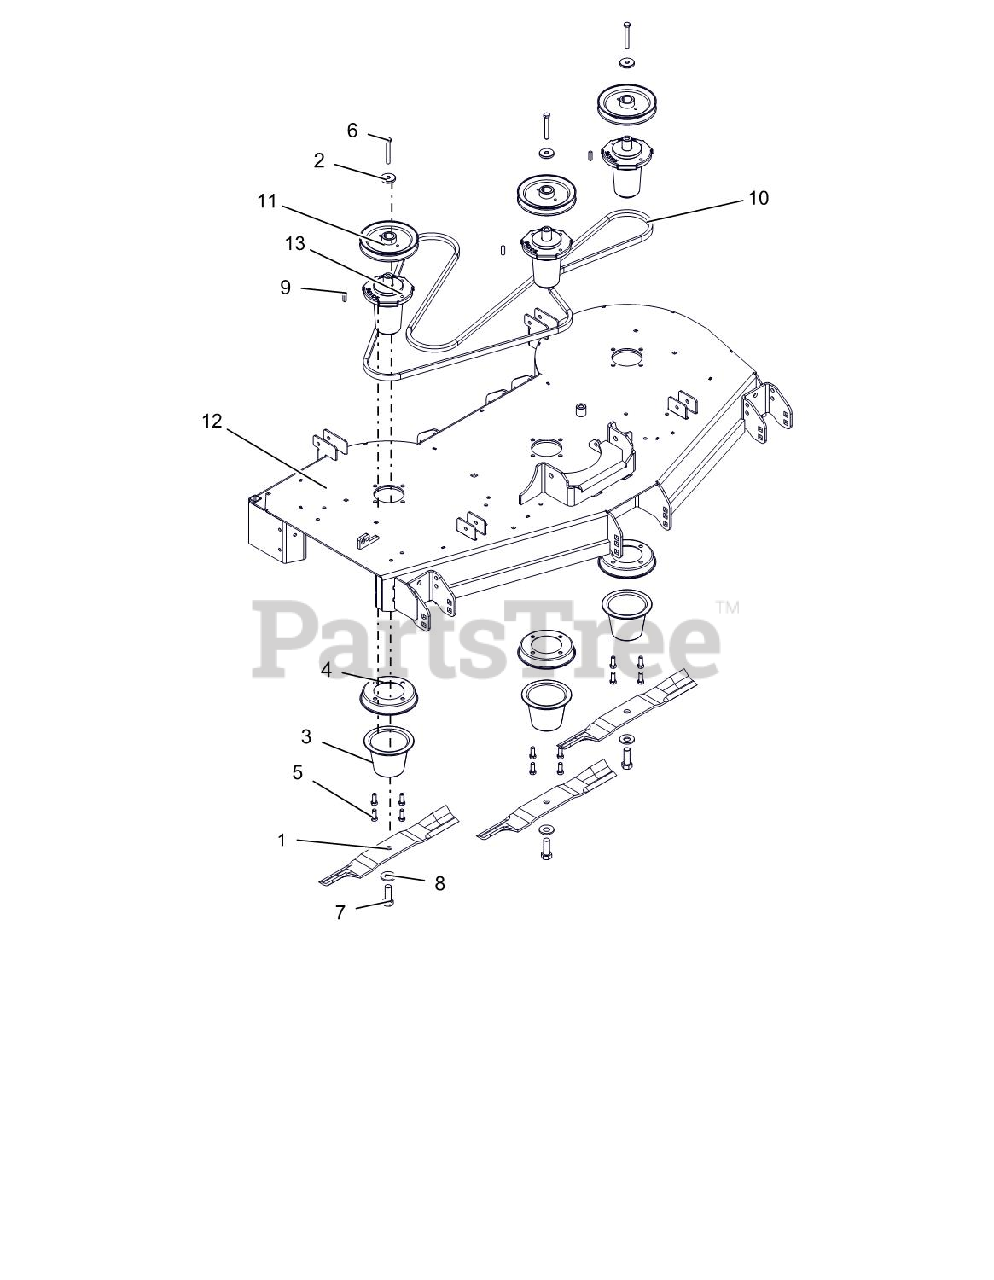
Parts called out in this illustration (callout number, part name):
1	BLADE, 18.00" MOWER (HI-LIFT)
2	RETAINER, SHEAVE
3	GUARD, SPINDLE LOWER
4	GUARD, SPINDLE TOP
5	BLT-HEX .38-16X1.0 GR8 YZ EP30
6	BLT-HEX .38-16X2.75 GR8 YWZC
7	BLT-HEX .62-18X1.75 GR8 YWZC
8	WSHR-BLVL .669X1.535X.138
9	KEY, SQ .25X.25X1.00 RC 40-50
10	BELT, B-SECTION EPDM RAW EDGE
11	PULLEY, 1.00 ID X 6.00 OD
12	KIT, 52" MOWER DECK W DECALS
13	ASM, MAINT FREE SPINDLE
